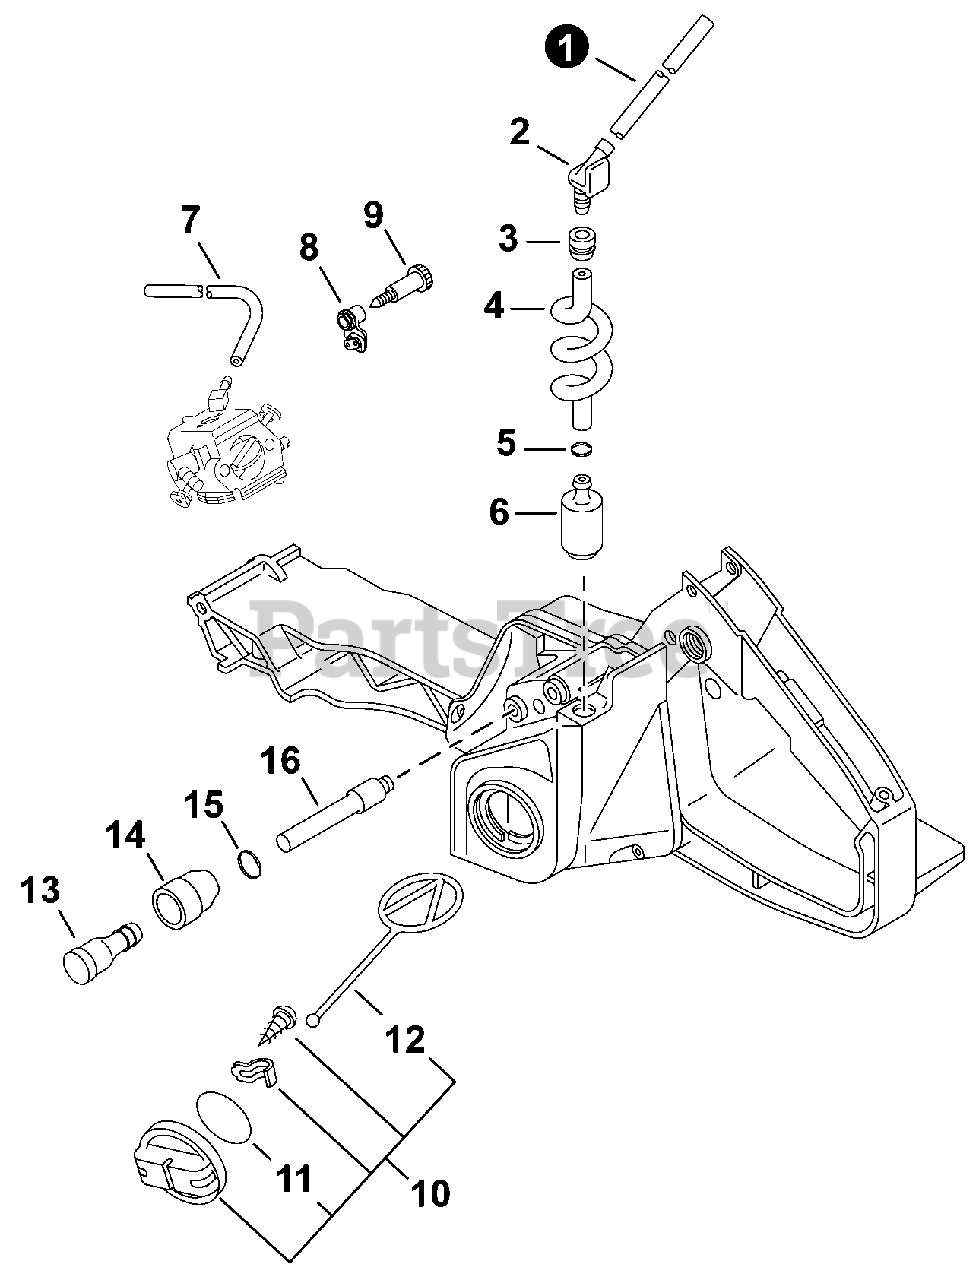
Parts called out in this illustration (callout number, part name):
1	PIPE, FUEL 3x6x120 BLACK
2	CONNECTOR, PIPE
3	GROMMET
4	PIPE, FUEL
5	CLIP 6.5 MM
6	FILTER, FUEL
7	PIPE, IMPULSE 3x6(8)x160
8	GROMMET, NEEDLE
9	SCREW, IDLE ADJUST - GRAY
9	SCREW, IDLE ADJUST - ORANGE
10	CAP ASSY, FUEL
11	O-RING 29
12	CONNECTOR, CAP L= 60 MM
13	VENT ASSY
14	HOLDER, VENT
15	CLIP 5.5
16	PIPE 3x5x90
